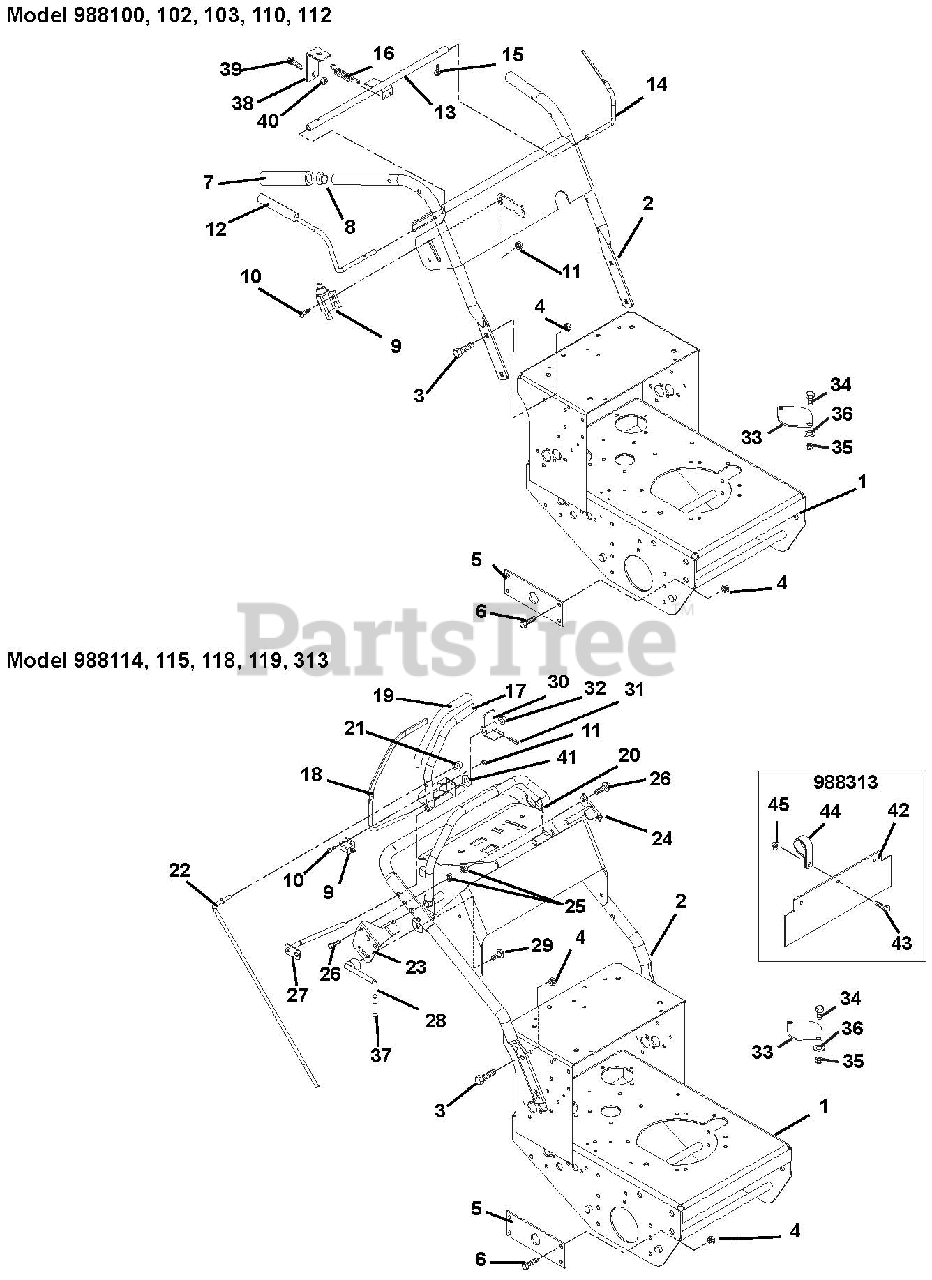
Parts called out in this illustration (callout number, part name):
1	Kit-Frame with Decals
2	Kit-Handlebar with Decals GR13
2	Kit-Handlebar with Decals GR15
2	Kit, Handlebar with Decals GR13/15-Pro Steer
3	Bolt-Hex .38-16 x 1.00 Grade 5
4	Nut-Locking-Nylon .38-16
5	Plate, Support
6	Bolt-Hex .38-16 x 1.00 Grade 5
7	Grip, Handlebar
8	Caplug, Handlebar
9	Switch, Double Pole
9	Switch, Single Pole
10	Screw, Machine 10-24 x .75 Hex Washer Head
10	Screw-Machine 10-24 x .75 Hex Washer Head
11	Nut-Locking-Nylon 10-24 with Insert
12	Lever, Right Hand-Operator Presence
13	Weldment, Pivot Tube
14	Lever, Left Hand-Operator Presence
15	Screw-Tapping 8-32 x .50 Hex Washer Head
16	Spring-Tension .047 x .438 x 1.45
17	Weldment, Lever-Right Hand Speed Control
17	Weldment-Lever-Left Hand Speed Control
18	Lever- Operator Presence
19	Grip- Handlebar
20	Weldment- Speed Control Stop
21	Ring-Retaining-External .375 x .010
22	Rod, Steering
23	Weldment, Control Stop Limiter-Right Hand
24	Weldment, Control Stop Limiter-Left Hand
25	Nut-Locking-Top-Flange .31-18
26	Bolt-Hex .31-18 x 1.75 Grade 5
27	Weldment, Speed Control Pivot- Right Hand
27	Weldment, Speed Control Pivot- Left Hand
28	Lever- Control Stop Lock
29	Bolt-Round Head Square Neck .38-16 x .75 Grade 2
30	Actuator, Switch
31	Pin-Roll .125 x .75
32	Nut-Push .312
33	Plate, Cover
34	Bolt-Hex .38-16 x .75 Grade 5
35	Nut-Locking-Flange .375-16
36	Washer-Flat-Steel .406 x .812 x .065
37	Grip, Hand Clutch Lever
38	Bracket, Brake Link
39	Bolt, Hex .25-20 x .75 Grade 5
40	Nut, Locking Nylon .25-20
41	Washer, Wave
42	Guard, Debris
43	Bolt-Hex .38-16 x .75 Grade 5
44	Clamp, Steel 1.0
45	Nut-Locking-Top-Flange .38-16
